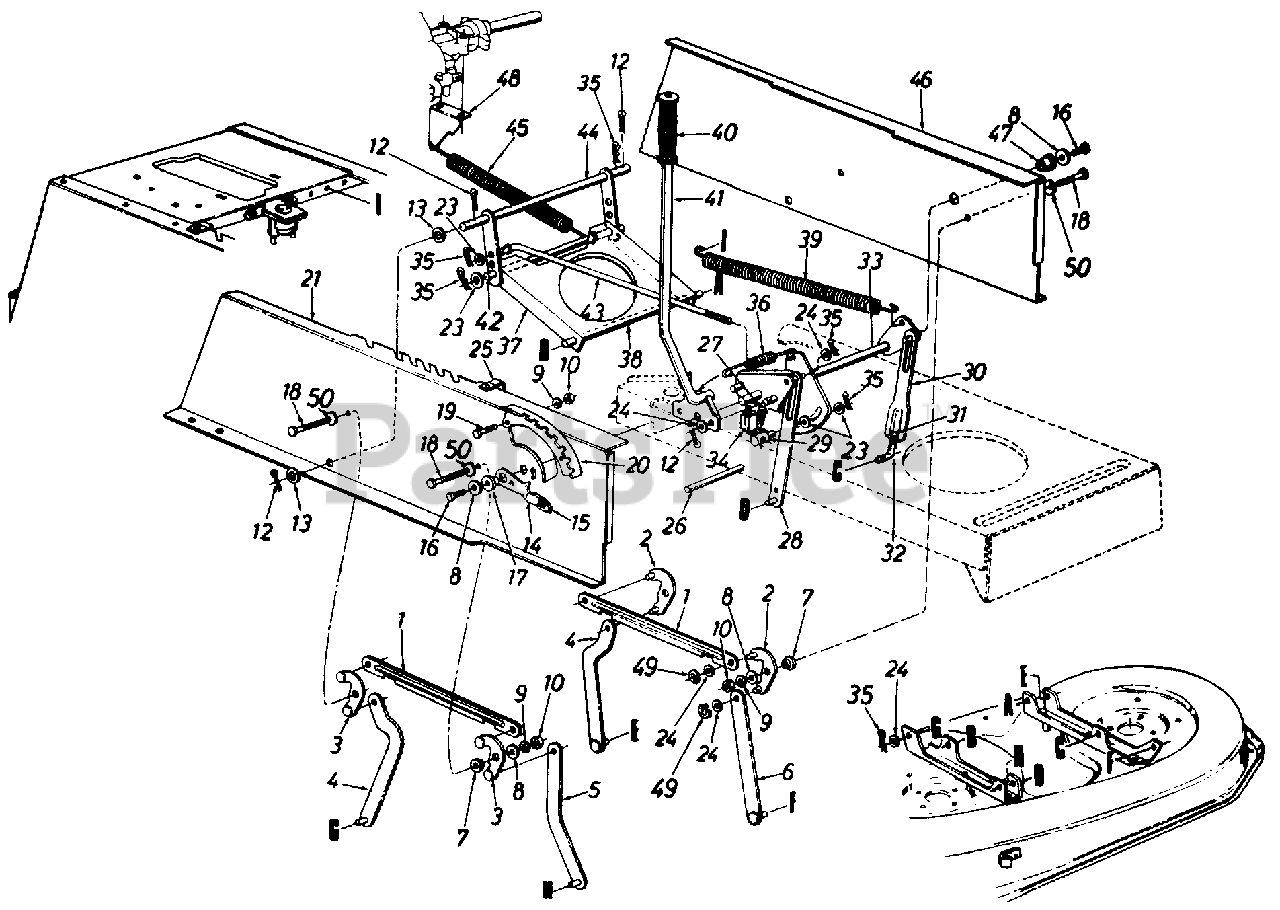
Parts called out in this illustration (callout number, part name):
3	Pivot Link Ass'y. - R.H.
7	Shld. Spacer .318" I.D.
8	Fl-Wash. .344" I.D. x .62" O.D.
9	L-Wash. 5/16" I.D.
10	Hex Nut 5/16-18 Thd.
12	Cotter Pin 1/8" Dia.
13	Fl-Wash. .635" I.D. x 1.0" O.D.
14	Height Adj. Stop Lever Ass'y.
15	Knob
16	Hex Wash. TT-Tap Scr. 5/16-18 x .75" Lg.
17	Flange Brg. .63" I.D.
18	Hex Wash. Hd. Scr. 5/16-18 x .875" Lg.
19	Hex Bolt 5/16-18 x .75" Lg.
20	Index Brkt.
24	Fl-Wash. .531" I.D. x .93" O.D.
25	Clamp
26	Running Board Rod
27	Hex Wash. Hd. Tap Scr.
31	Hex Nut 1/2-20 Thd. (Gr. 5)
32	Lift Link Adjuster
35	Inter. Cotter Pin 3/8" Dia.
36	Extension Spring
39	Extension Spring
40	Grip (Lift Handle)
41	Deck Lift Handle Ass'y.
42	Shaft 3/8" Dia. x 9.34" Lg.
43	Disengagement Rod
44	Stabilizer Shaft Ass'y.
45	Extension Spring 7.58" Lg.
48	Spring Retainer Brkt.
49	"E"-Ring
50	Bell-Wash. .325" I.D.
